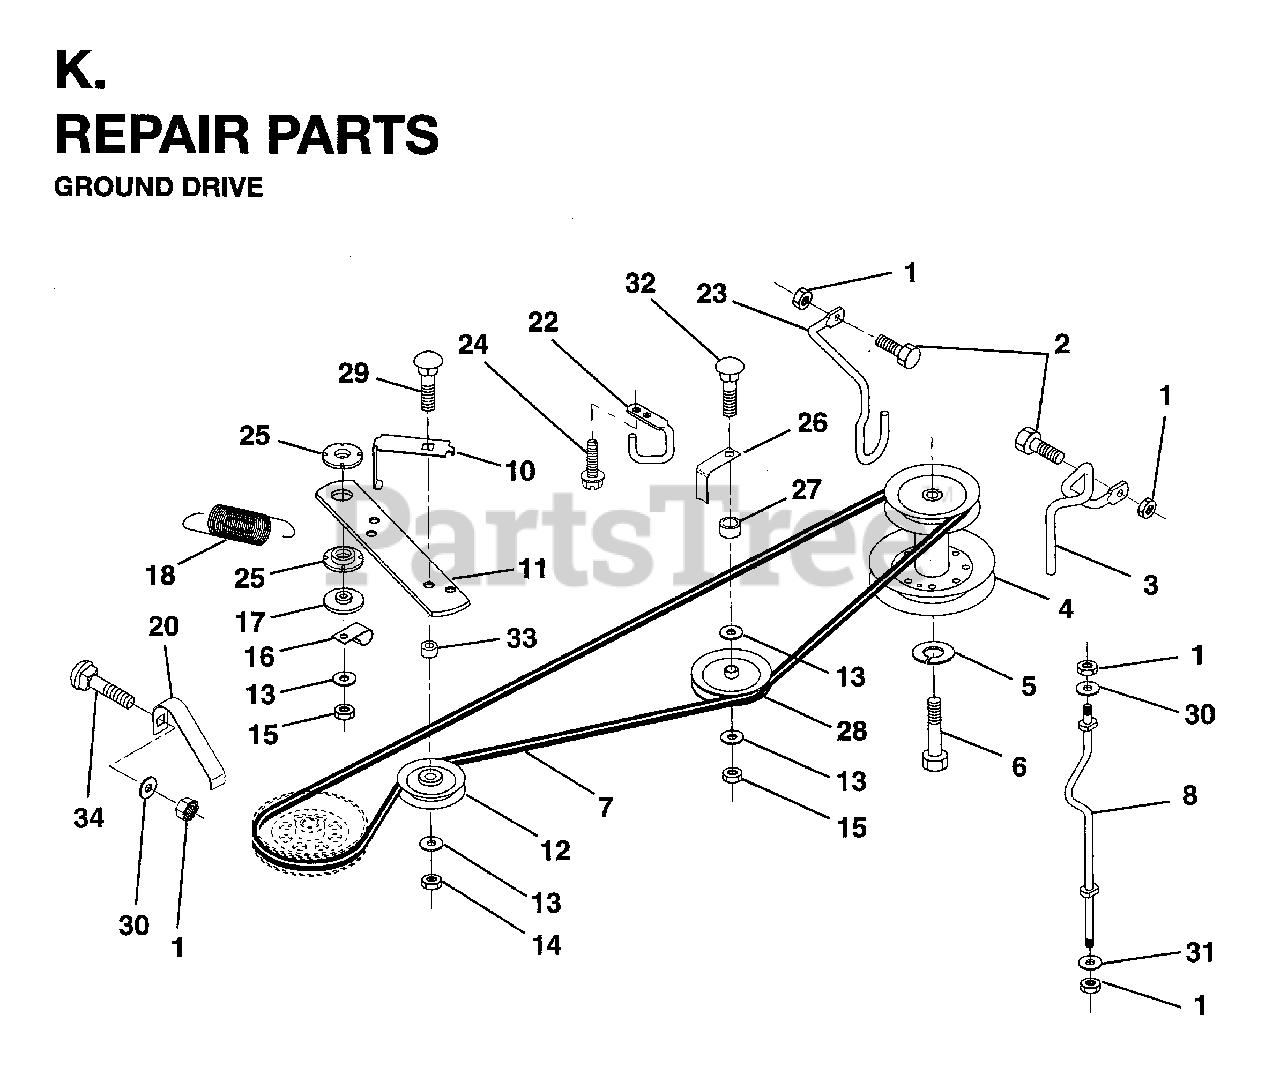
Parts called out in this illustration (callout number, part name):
1	NUT.71038.31-18.HEX.NYLOCK
2	BOLT
4	ENGINE PULLEY
5	LOCKWASHER
7	V-BELT 77.75
10	KEEPER, BELT
11	ARM, GROUND DRIVE CLUTCH
12	PULLEY.IDLER.FLAT
13	WASHER
14	LOCKNUT
15	LOCKNUT
16	CLIP,INSULATOR
17	SPACER, RETAINER
18	SPRING.EXTENSION
20	KEEPER, BELT
22	KEEPER,FRA DR BEL
23	KEEPER-MOWER DRIVE LH
24	BOLT
25	BUSHING NYLON COLLERED
26	KEEPER, BELT
28	PULLEY.IDLER.V.
29	BOLT
30	WASHER - 15X7.3X1.6
31	WASHER - 15X7.3X1.6
32	BOLT
33	SPACER NLA
34	BOLT
